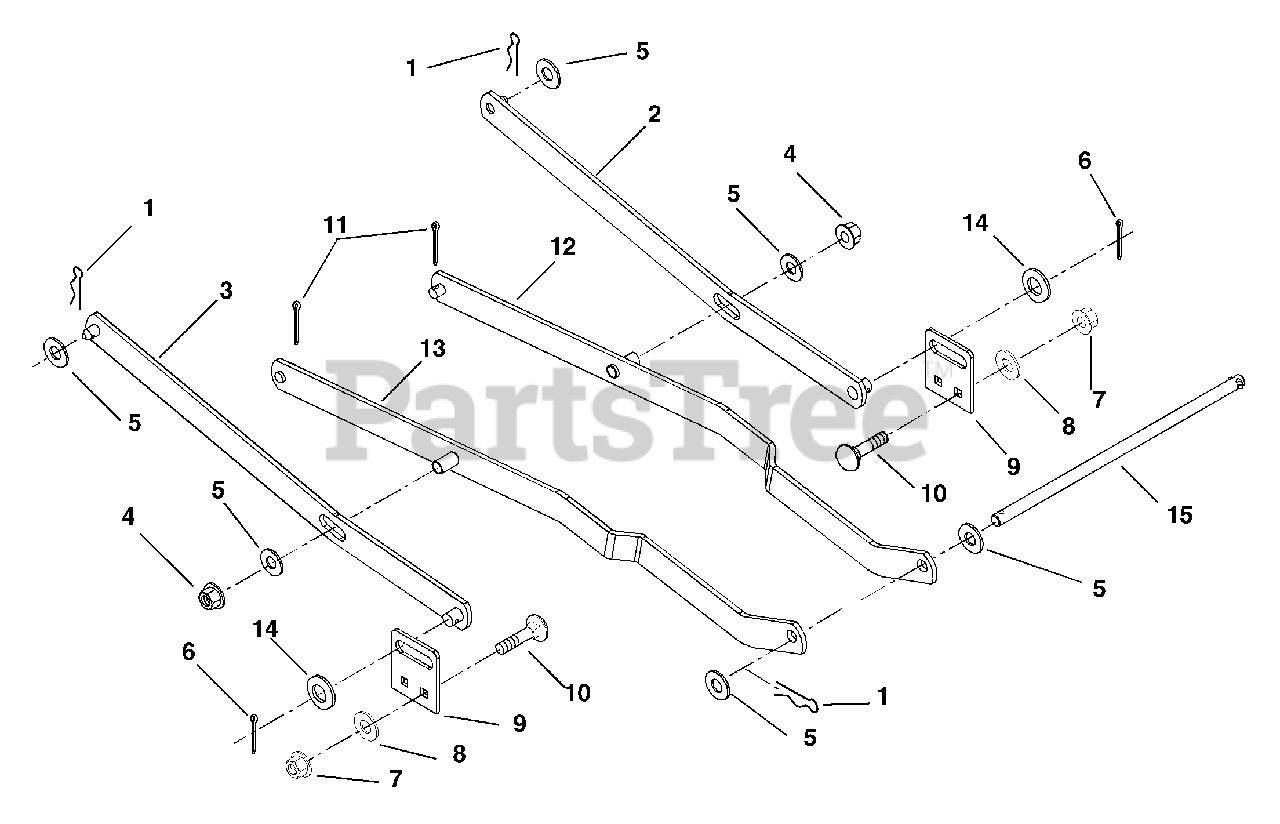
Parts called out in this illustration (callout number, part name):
1	PIN-HAIR-EXT .12X.31X2.37 YWZC
2	ARM, LIFT-LEFT REAR
3	ARM, LIFT-RIGHT REAR
4	@NUT-LK-CTR .62-11 YWZC
5	@WSHR-FL-STL.656X1.31X.095 YWZ
6	@PIN-CTR .16X1.25 EXTPRSQCT YZ
7	NUT-LK-CTR .375-16 YWZC
8	@WSHR-FL-STL.406X.812X.065 YWZ
9	ADJUSTOR-PAN
10	@BLT-RDHDSQNK .38-16X1.00 G2YZ
11	@PIN-CTR .12X1.25 EXTPRSQCT YZ
12	ARM, LIFT-RIGHT FORWARD
13	ARM, LIFT-LEFT FORWARD
14	@WSHR-FL-STL.531X1.06X.095YWZC
15	ROD-DECK HANGER, FRONT
